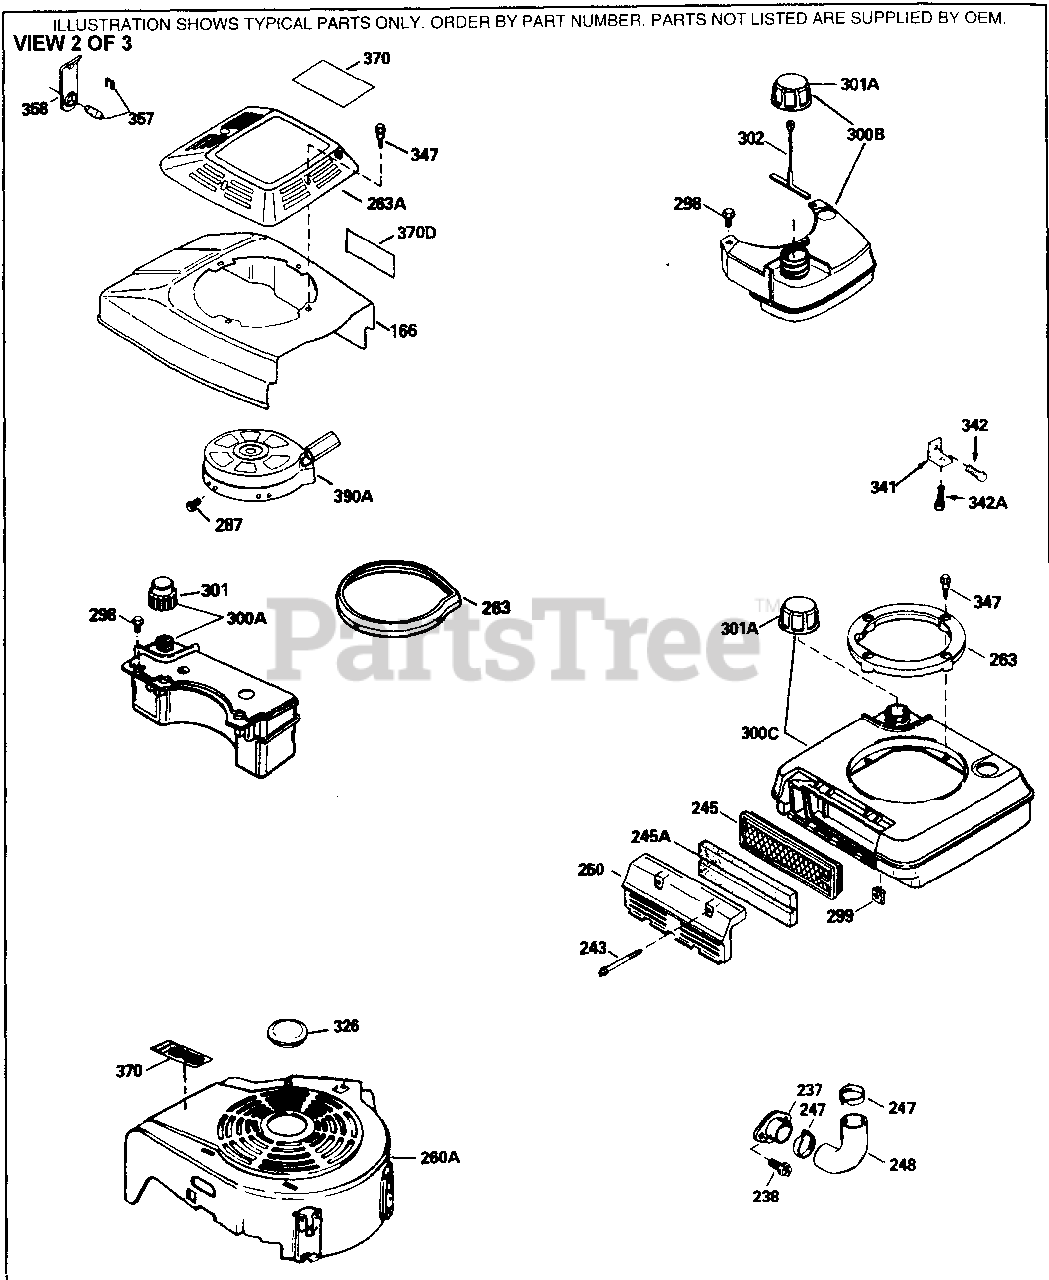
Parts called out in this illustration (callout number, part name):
166	Shroud, Engine
238	Screw, 10-32 x 49/64"
245	Air Filter (Paper) (also available in Packaged Part #740095 (Qty.2))
246D	Filter, Pre-Air (Optional)
250A	Air Filter Cover (Craftsman)
263A	Grill, Starter
287	Screw, 8-32 x 1/2"
301A	Fuel Cap (Red)
347	Screw, 10-32 x 27/32"
354	Staple (Not used on all models)
357	Rope Stop & Staple Assy. (Incl. 354)
370G	Decal, Instruction (Optional)
390A	Rewind Starter Refer to Division 5, S ection C, page 34 or Fiche 8A, Grid G -5 for breakdown
999	Summer Maintenance Kit (incl. Oil, Sp ark Plug, Air Cleaners (2), & Ultra-F resh)
